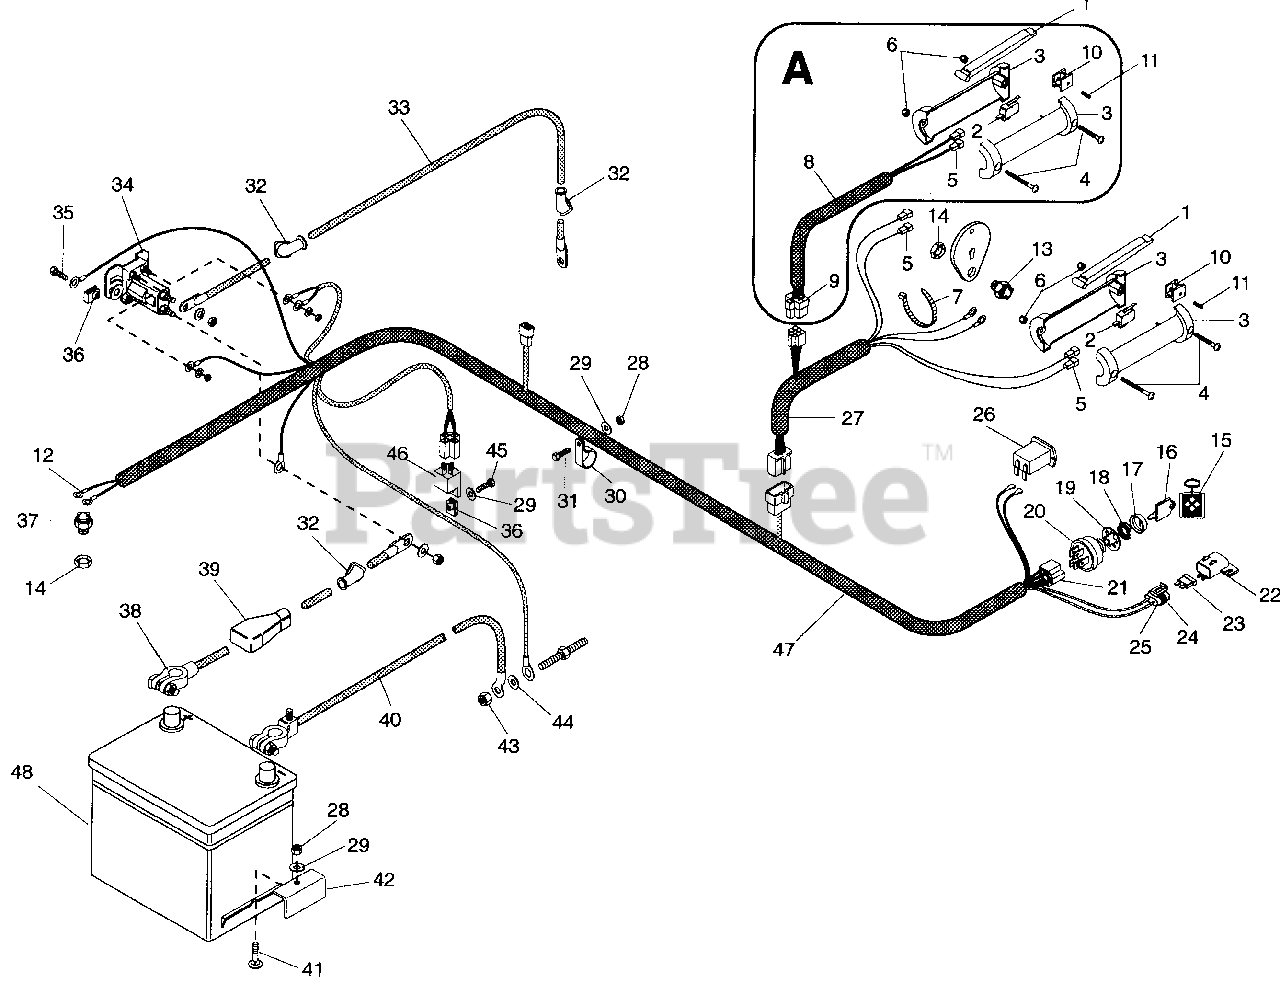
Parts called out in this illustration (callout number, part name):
1	Lever
2	Switch
3	Handle, Left Hand & Right Hand
4	Screw-Machine 10-24 x 1.50
5	Terminal, Female
6	Nut-Locking 10-24
7	Tie Wrap, Black
8	Harness Steering Brake
9	Connector
10	Holder Switch
11	Pin-Roll .094 x .750
12	Terminal, Eyelet
13	Switch, Interlock Closed
14	Nut-Stamped .56-18
15	Key Chain
16	Ignition Switch Key
17	Cap-Ignition Switch
18	Nut-Panel .562-24 Greco
19	Washer-Lock-Internal .563 x .040
20	Ignition Switch
21	Connector
22	Cover
23	Fuse, 25 Amp
24	Terminal For 10-12 GA Wire
25	Assembly, Connector Weather Tight
26	Hour Meter
27	Harness, Wiring Handlebar
28	Nut-Locking Nylon .250-20
29	Washer Flat Steel .281 x .62 x .062
30	Clamp, Cushioned Steel
31	Bolt-Hex .25-20 x .75
32	Boot, Insualtor
33	Cable, Battery to Solenoid
34	Solenoid
35	Bolt-Hex .25-20 x .63
36	Nut-Speed .25-20
37	Switch, Interlock Open
38	Cable, Positive Battery
39	Cover, Battery Terminal
40	Cable, Negative Battery
41	Bolt-Round Head Square Neck .25-20 x 1.75
42	Clamp
43	Nut-Locking-Nylon .375-16
44	Washer-Flat-Steel .406 x .812 x .065
45	Bolt-Hex .25-20 x .63
46	Relay
47	Harness, 10, 12 & 16 HP Electric
48	Battery, 12 Volt
